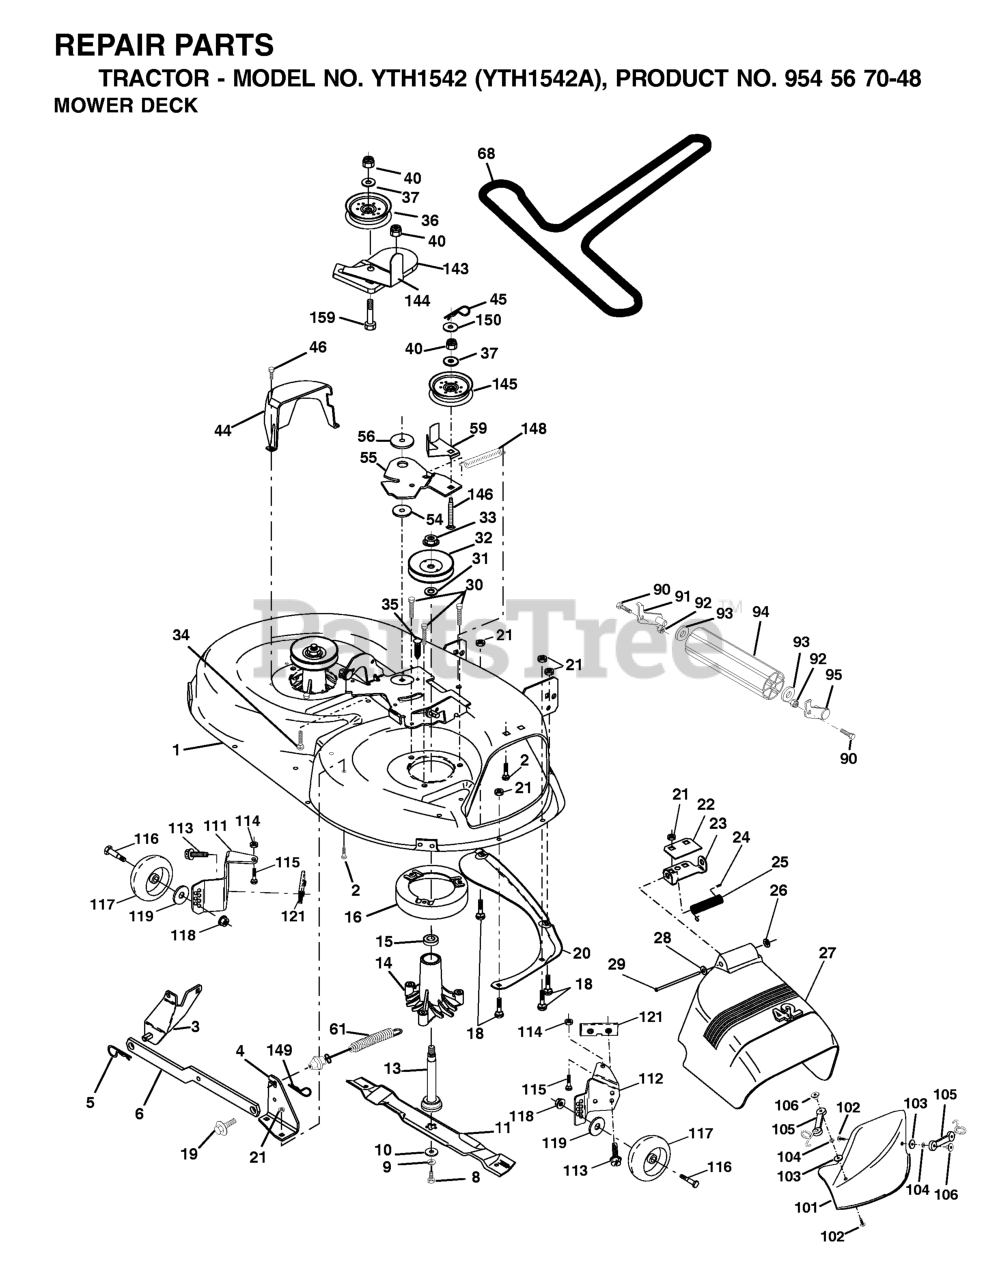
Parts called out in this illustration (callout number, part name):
1	DECK SVC 42"
2	RP BOLT 5/16-18 X3/4 ZN/YEL GR
3	BRKT ASM SWAY BAR
4	BRACKET ASM DECK 42"
5	RETAINER-SPRNG RB
6	REAR SUSP ARM
8	BLADE BOLT
9	LOCKWASHER
10	WASHER.BLADE
11	Blade Mower 42" High Perf.
13	SHAFT ASM VENT
14	HOUSING.MANDREL.VENTED (MACHD)
16	STRIPPER
18	BOLT
19	BOLT SHD 5/16-18
20	BAFFLE.VORTEX
21	LOCKNUT
24	CAP-SLEEVE LT
25	SPRING TORSION
26	NUT PUSH M
28	Washer 11/32 x 5/8 x 16 Ga SD
29	ROD.HINGE
30	SCREW THDROL ROLLING WASHER HD
31	WASHER
32	PULLEY MANDREL
33	NUT
35	FASTENER.XMAS.TREE
36	PULLEY.IDLER.FLAT
37	WASHER
44	GUARD MANDREL LH BLACK
45	RETAINER M
46	SCREW.1/4-20X5/8
54	HARDENED WASHER
55	ARM IDLER 42"
56	SPACER.RETAINER.MOWER
59	GUARD TUV IDLER
61	SPRING EXT ELEC CLUTCH
68	V-BELT PRIMARY 42"
90	BOLT
91	BRACKET LH (A)
92	NUT
93	Washer 1 17/32 X 7/8 X 16 Ga
94	NOSE ROLLER
95	BRACKET RH (B)
101	COVER MULCH 42"
102	SCREW
104	LOCKWASHER #10
105	LATCH ASSY
106	WELDNUT
113	Screw Tapping 5/16-18 Unc
114	NUT
115	BOLT.CARR.5/16-18X1/2
116	BOLT, SHOULDER
117	WHEEL.GAUGE.STANDARD
118	LOCKNUT
119	WASHER.5/16.FLAT.STE.STD.
143	BRKT ARM IDLER 42"
144	KEEPER BELT 42" CLUTCH
145	PULLEY.IDLER.FLAT.PLATED
146	BOLT, CARRIAGE IDLER BLACK
148	IDLER RETURN SPRING
149	SPRING.RETAINER.YELLOW.ZINC
532134149	BLADE.42".MULCH
